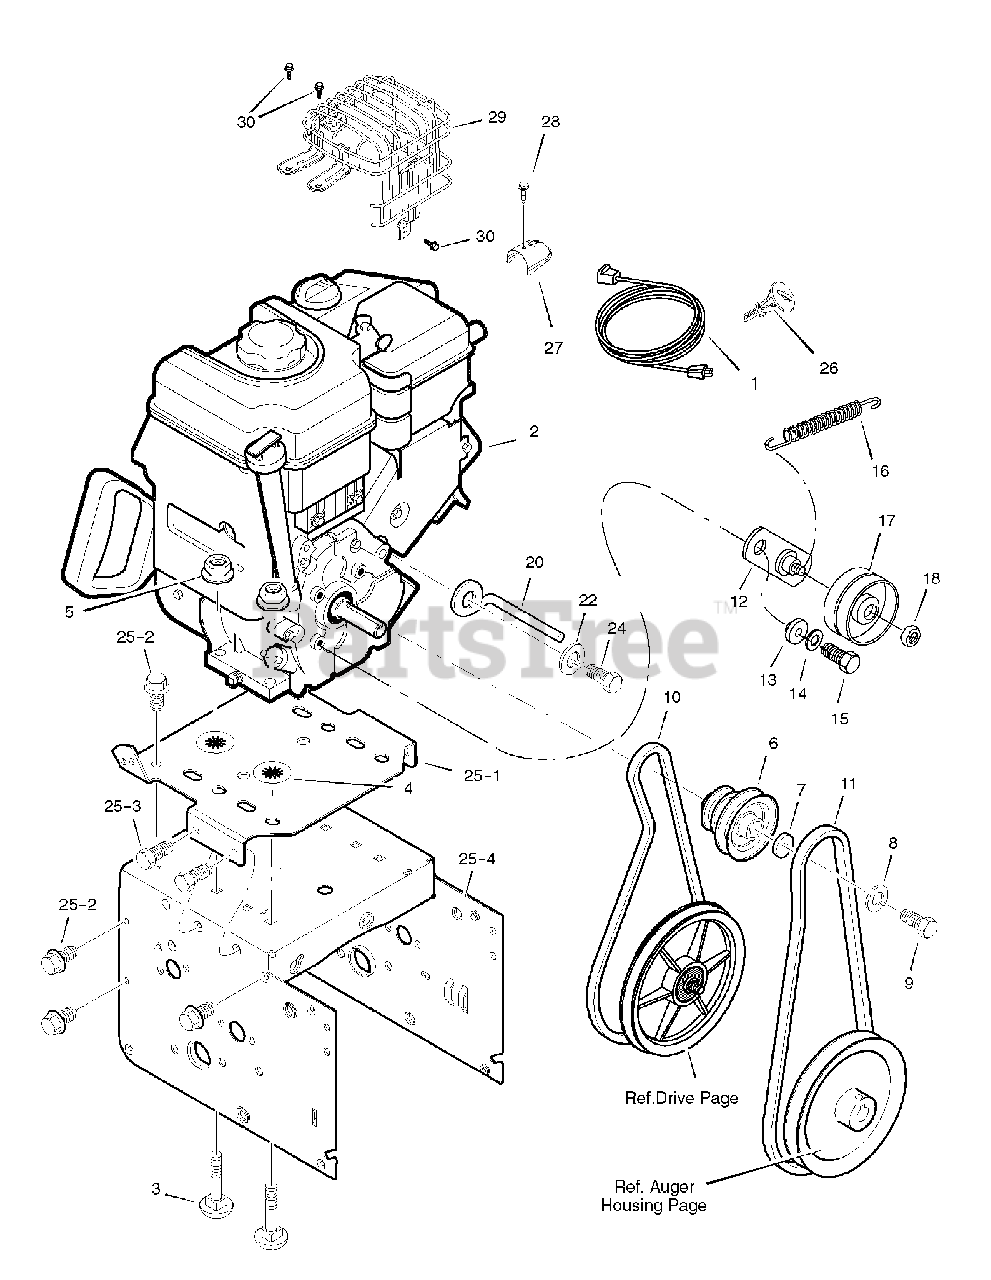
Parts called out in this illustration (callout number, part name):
1	CORD, Starter
2	* ENGINE, B&S Mod. 12D116-0124-E8
3	BOLT, CARRIAGE 5/16-18
4	RETAINER, PUSH
5	NUT, 5/16-18
6	PULLEY, ENGINE
7	WASHER
8	WASHER, .38ID
9	SCREW, 3/8-24 x 1.00
10	BELT, V 3L
11	BELT, V 4L
12	BRACKET ASSEMBLY, IDLER
13	BUSHING, IDLER BRACKET
14	WASHER, SPLIT
15	SCREW, 5/16-24 X 0.75
16	SPRING, IDLER TRACTION DRIVE
17	PULLEY, IDLER
18	NUT, JAM 3/8-16
20	GUIDE, BELT
22	WASHER .31X.58X.08
24	SCREW, 5/16-24 x 0.75
25-1	PLATE, ENGINE MOUNT
25-2	SCREW, TAP 1/4-20 X .63
25-3	SCREW, TAP 5/16-18 X .50
25-4	FRAME, MOTOR BOX
26	KEY, BRIGGS ENGINE
27	DEFLECTOR, Muffler
29	HEAT SHIELD, Muffler
30	SCREW, Hex-Washer
